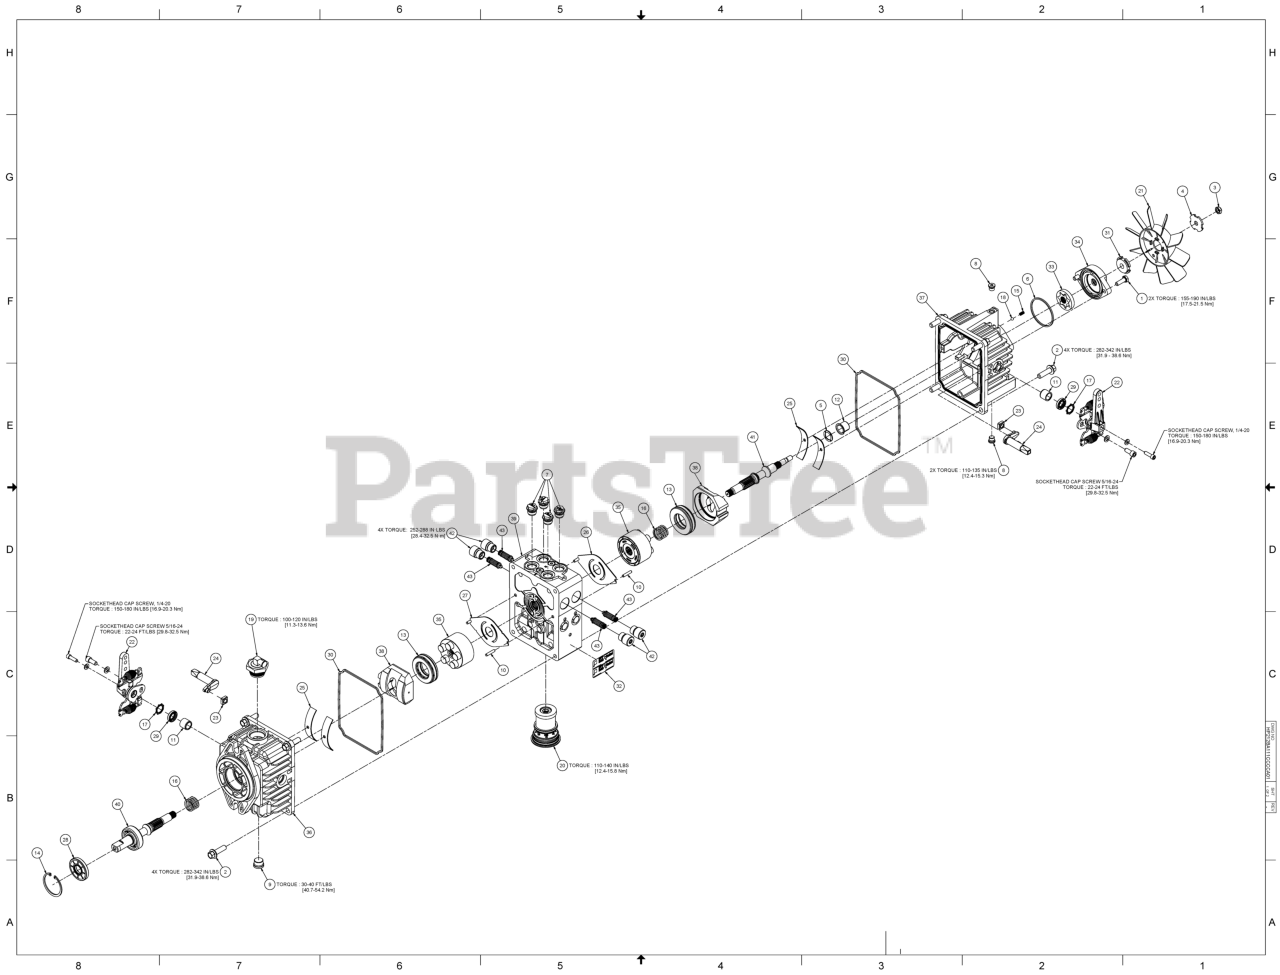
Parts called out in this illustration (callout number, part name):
1	SCREW (CHARGE PUMP)
2	SCREW (10MM)
3	STOP NUT (FAN DRIVE)
4	WASHER (FAN DRIVE)
6	O-RING (CHARGE PUMP)
7	PORT PLUG (3/4-16)
8	HOLLOW HEX PLUG ASSM
9	3/14-16 HOLLOW HEX PLUG
10	DOWEL PIN
11	BUSHING (TRUNNION ARM)
12	BUSHING
13	THRUST BEARING ASSM
14	INTERNAL RETAINING RING
16	SPRING (CENTRAL)
17	RETAINING RING (TRUNNION ARM)
18	BALL - 1/4"
19	ADAPTOR ASSM
20	FILTER- HP2 OIL
22	SA- RTN - (RH)
23	CONTROL BLOCK
24	TRUNNION ARM, MACHINED
25	CRADLE BUSHING
26	PORT PLATE CW
27	PORT PLATE CCW
28	SEAL (SHAFT)
29	SEAL (TRUNNION ARM)
30	SEAL (TANDEM PUMP-HOUSING)
31	FAN SPACER
32	LABEL
33	ROTOR SET ASM
34	CHARGE PUMP ASM(3.2CC FAN DRI)
35	PISTON & BARREL ASM 12CC
36	FRONT HOUSING
37	REAR HOUSING
38	SWASH BLOCK ASM
39	CENTER BLOCK ASM
40	SHAFT ASM (20MM DOUBLE D)
41	SHAFT (REAR FAN DRIVE)
42	PLUG & O-RING ASM
43	RELIEF VALVE SA .024"
